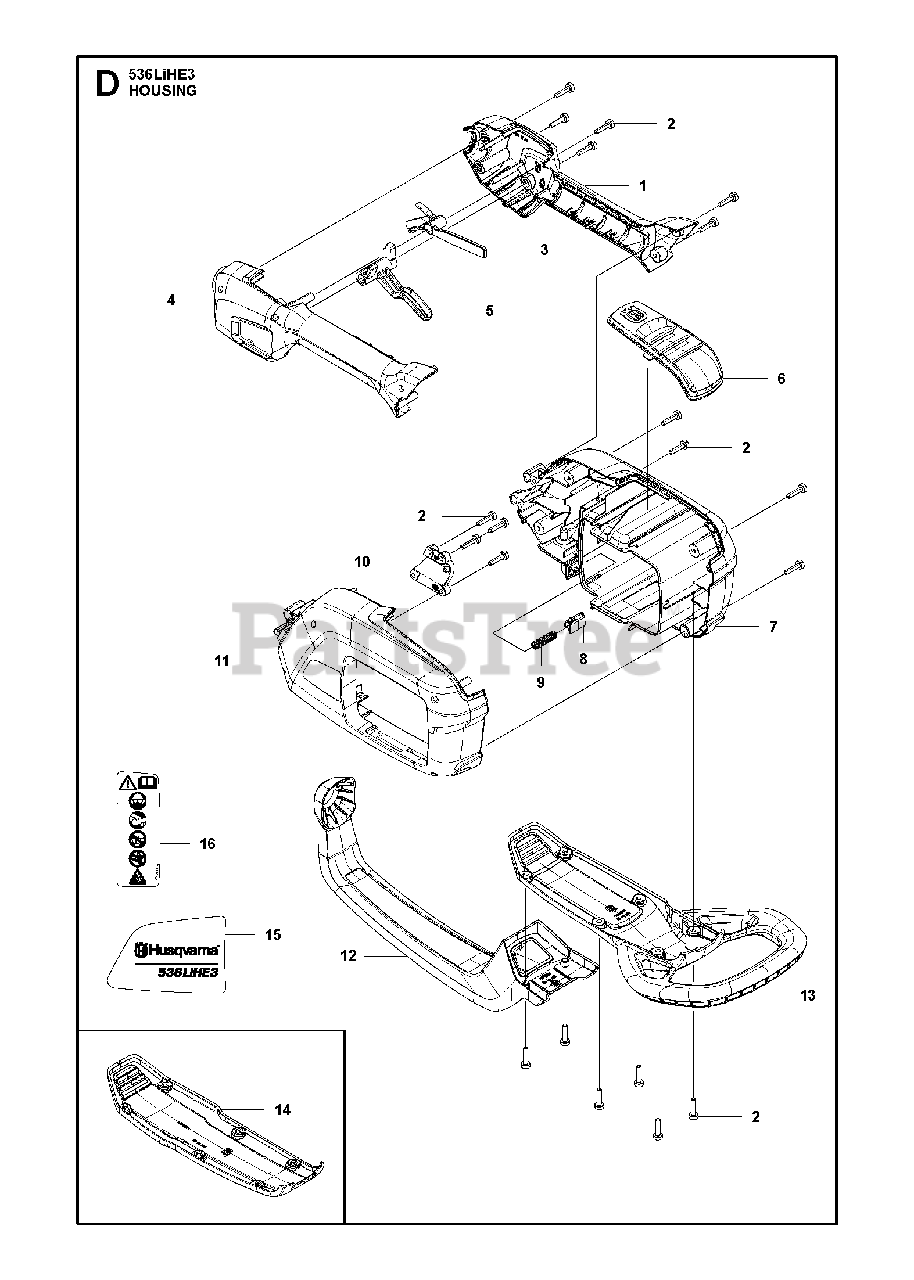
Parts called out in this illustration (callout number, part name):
1	Right Half Handle
2	SCREW
3	THROTTLE LOCKOUT
4	HANDLE HALF LEFT
5	TRIGGER
7	Housing, RH
8	PUSH BUTTON
9	SPRING PUSH OUT
11	HOUSING LEFT
12	TRIGGER GUARD
13	BUMPER SKID PLATE
14	SKID PLATE
